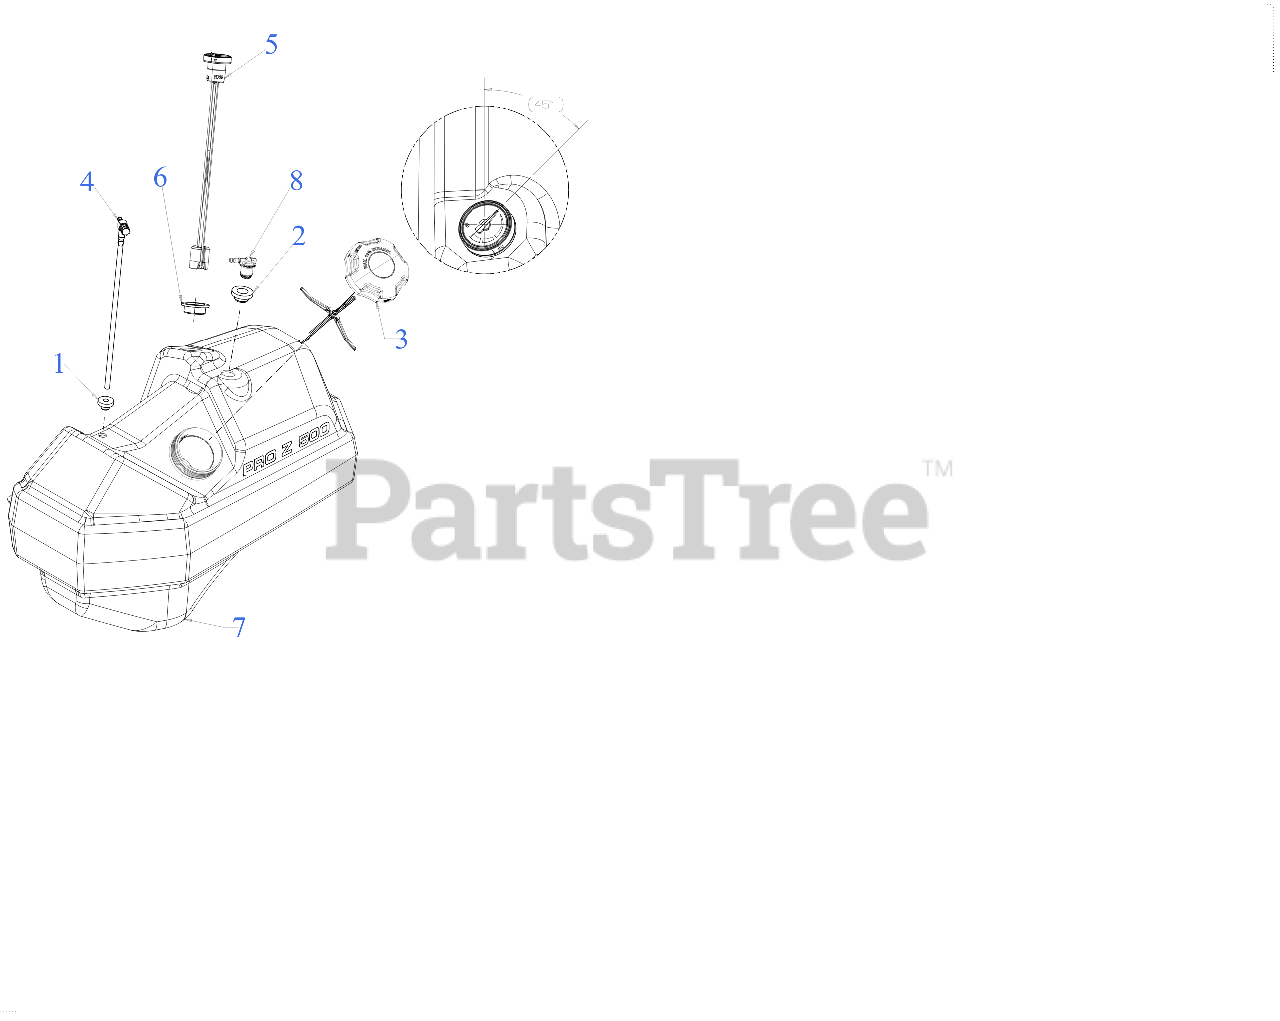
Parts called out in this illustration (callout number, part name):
1	GROMMET-FUEL TANK
2	GROMMET .755 x .955 x .55
3	FUEL CAP - 3.50" ONE WAY VENT
4	FUEL PICKUP VALVE
5	FUEL GAUGE
6	FUEL GAUGE GROMMET
7	FUEL TANK
8	FUEL VENT FITTING
